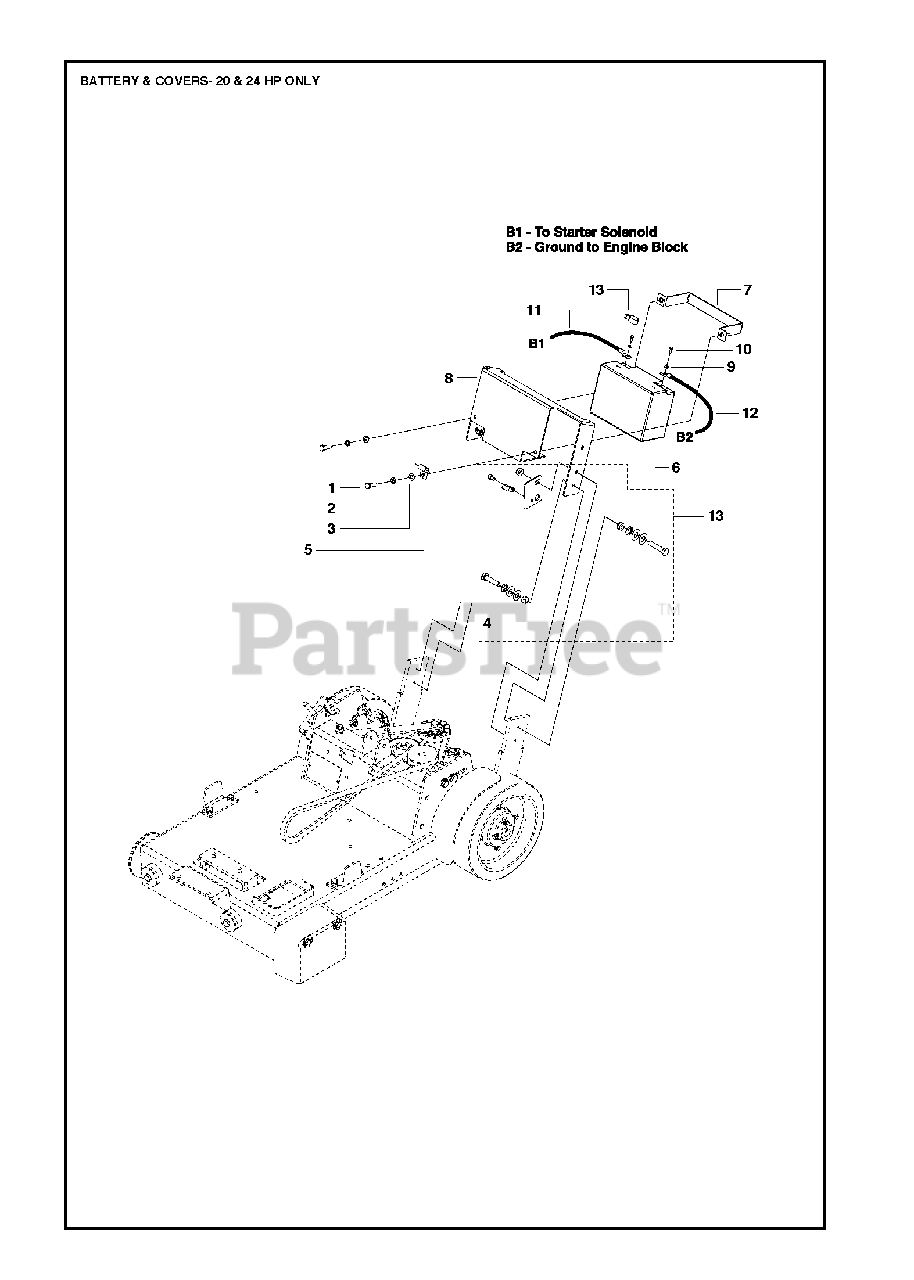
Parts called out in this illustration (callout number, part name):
2	SPRING WASHER
3	WASHER
4	HEXAGON LOCKING NUT
